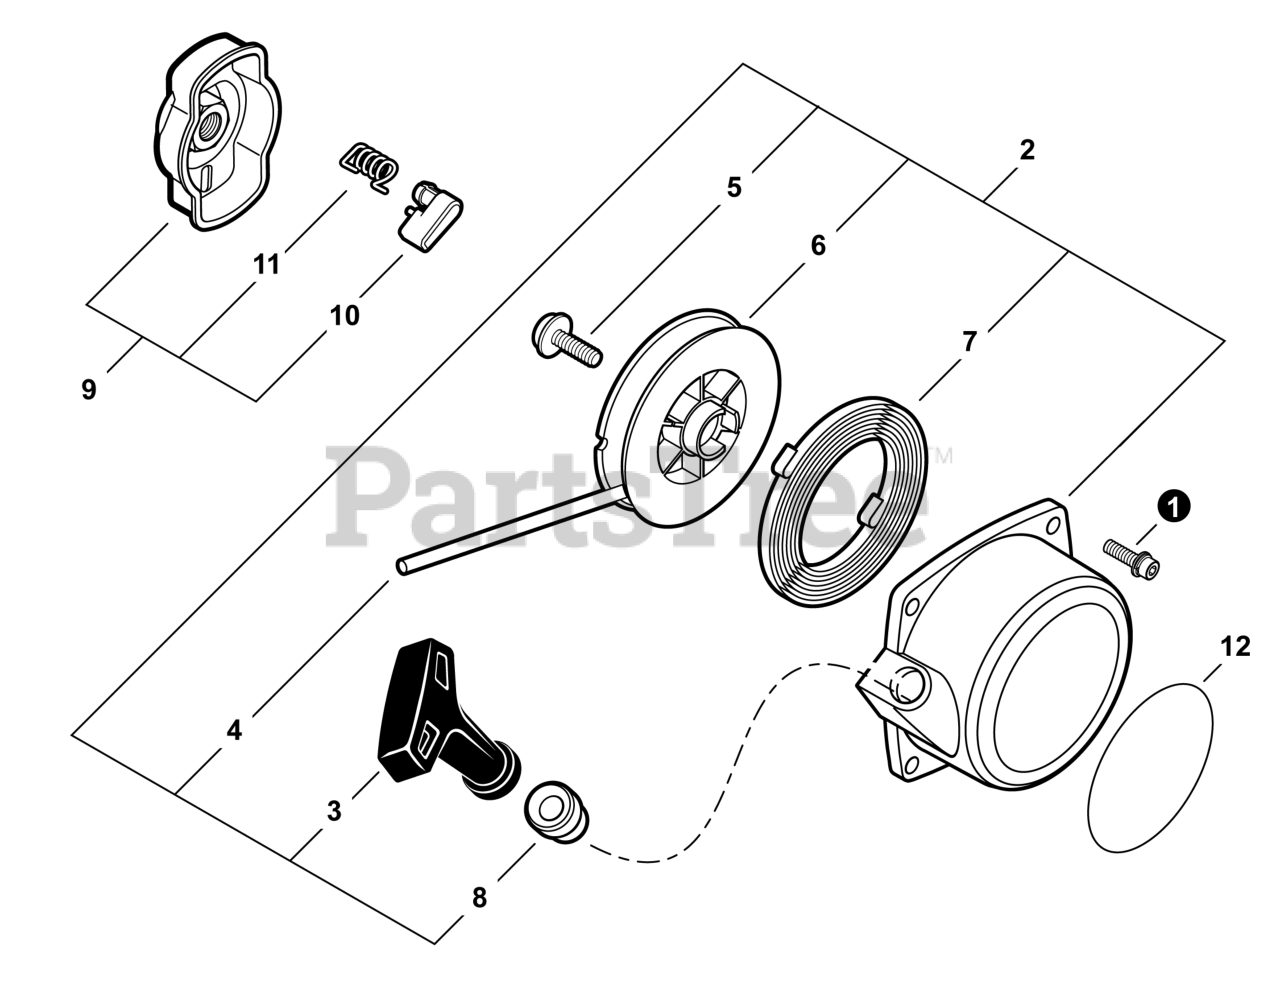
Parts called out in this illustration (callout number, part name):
1	SCREW 4×16
2	STARTER ASSY, RECOIL
3	GRIP, STARTER
4	ROPE, STARTER 3.0×1000
6	REEL, ROPE
7	SPRING, RECOIL
8	GUIDE, ROPE
9	PAWL ASSY, STARTER
10	PAWL, STARTER - BLACK
11	SPRING, RETURN
12	LABEL - ECHO
